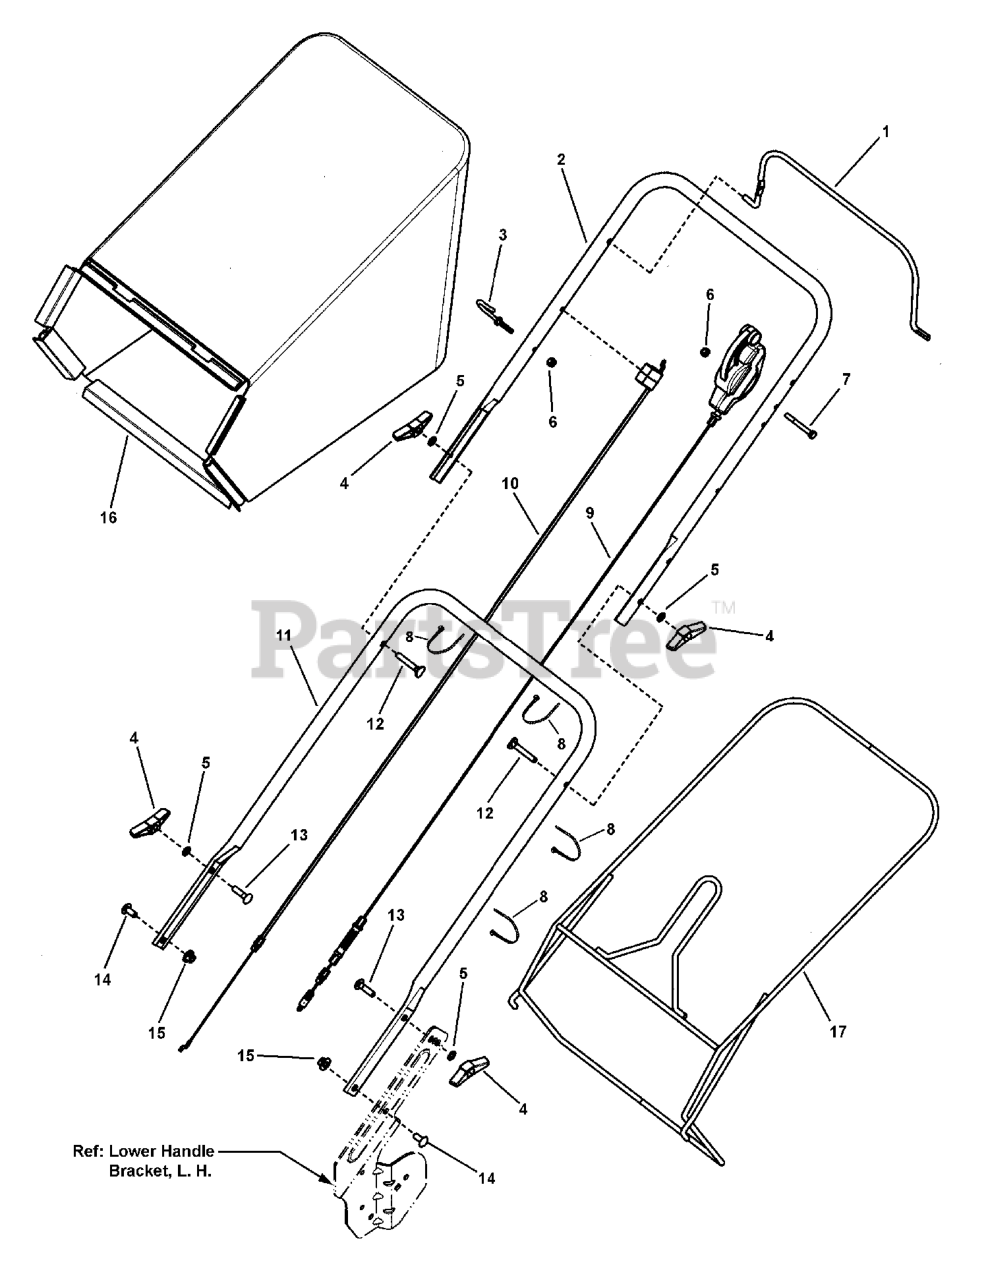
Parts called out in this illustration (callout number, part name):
1	BAIL, OPC Propelled
2	UPPER HANDLE, Propelled
3	GUIDE, Rope (1/4-20 thread)
4	KNOB, Wing, 5/16-18
5	WASHER, Internal Tooth Lock, 5/16"
6	NUT, 1/4-20 Nyloc
7	CAPSCREW, Hex Head, 1/4-20 x 2-1/4", GR 5
8	WIRE TIE, 11 Inch Std Black Nylon
9	CONTROL, Drive, Single Speed
10	CABLE, Bail, HW Propelled, Hi-Wheel
11	HANDLE, Lower
12	BOLT, Curved Head Square Neck, 5/16-18 x 2", GR 2
13	BOLT, Carriage, 5/16-18 x 1
14	BOLT, Carriage, 5/16-18 x 3/4"
15	NUT, Hex, 5/16-18
16	BAG, Cloth, Grass Bag, Murray
17	WELDMENT, Frame, Grass Bag
